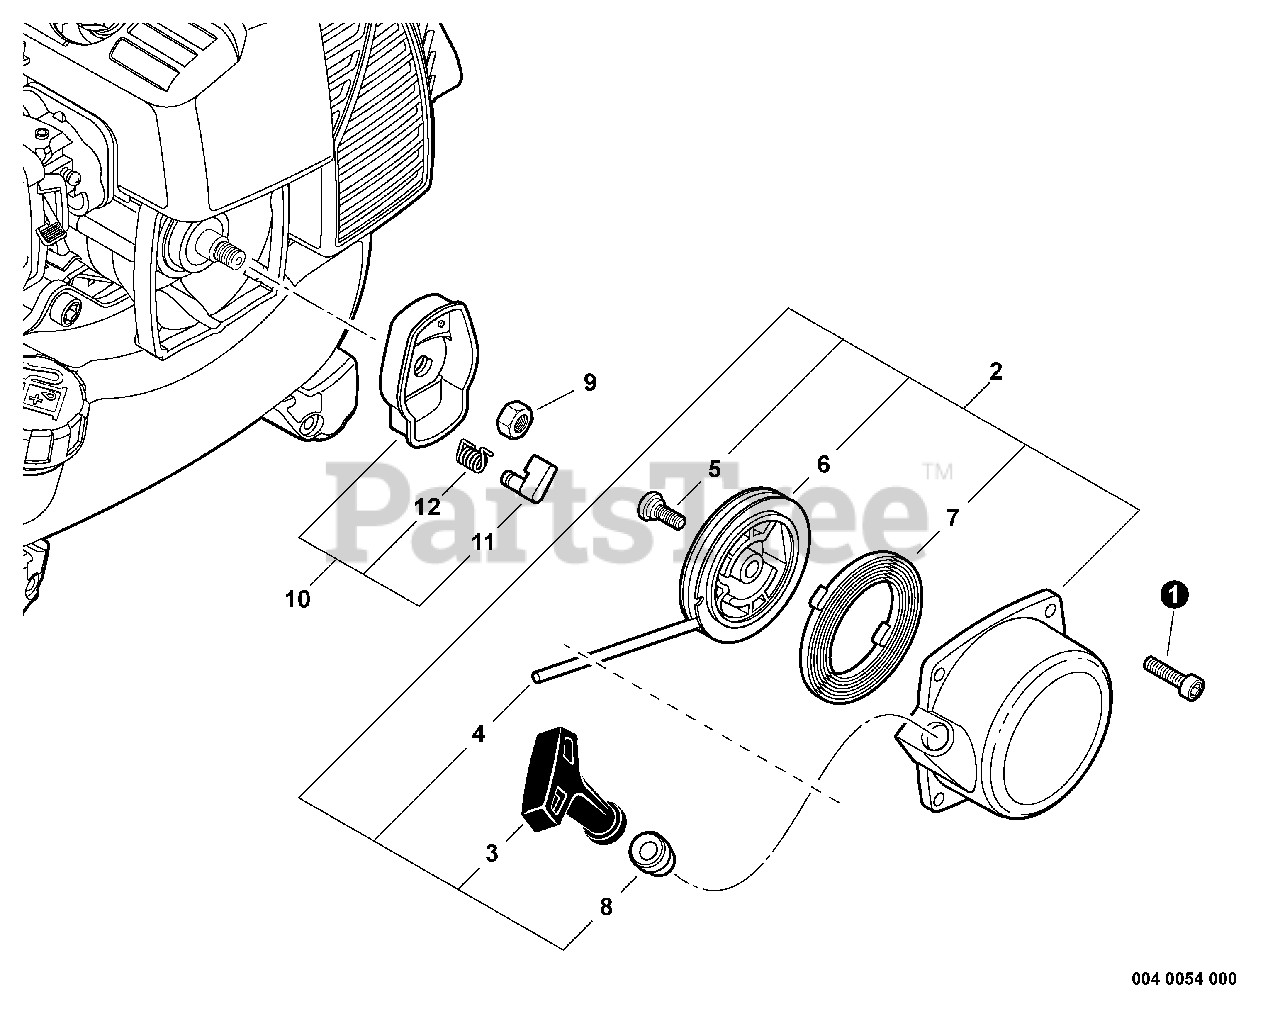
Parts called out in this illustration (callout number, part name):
1	BOLT, TORX 4×16
2	STARTER ASSY, RECOIL
3	GRIP, STARTER
4	ROPE, STARTER 3.0×1000
5	SCREW
6	REEL, ROPE
7	SPRING, RECOIL
8	GUIDE, ROPE
10	PULLEY ASSY, STARTER
11	PAWL, STARTER - BLACK
12	SPRING, RETURN
